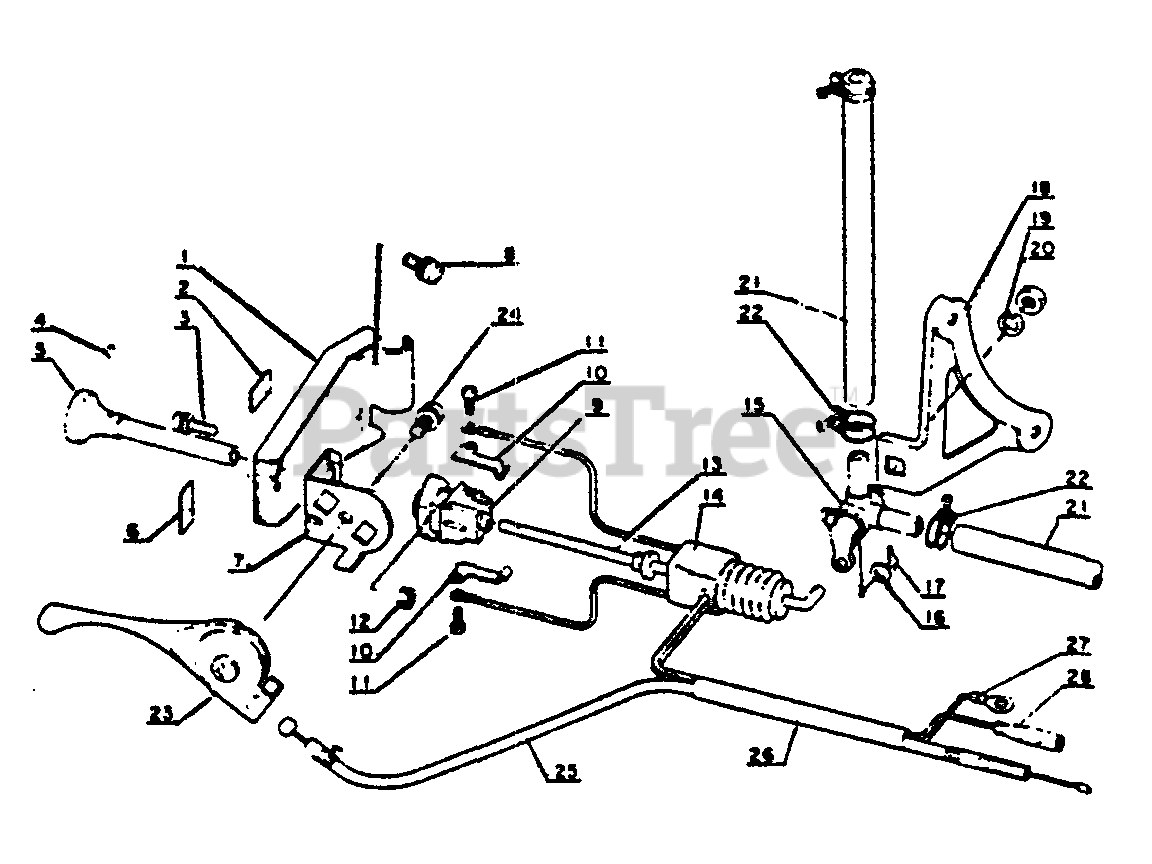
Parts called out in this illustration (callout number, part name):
1	BRACKET, SWITCH
2	LABEL - STOP
3	SCREW - 4X12
4	PIN - SPRING -- 1.6X10
5	KNOB
6	LABEL - SAFETY
7	BRACKET, THROTTLE LEVER
8	SCREW - 5X10
9	BODY, SWITCH
10	CONTACT, SWITCH
11	SCREW - 3X6
13	ROD
14	BRACKET, SWITCH
15	FUEL VALVE ASSY
16	WASHER - 4
18	BRACKET, FUEL VALVE
19	LOCKWASHER - 6
21	PIPE - FUEL
22	RETAINER, PIPE
23	LEVER, THROTTLE
24	SCREW - 5X12
25	THROTTLE CONTROL ASSY
26	CABLE, THROTTLE
27	LEAD - GROUND
28	LEAD - IGNITION
